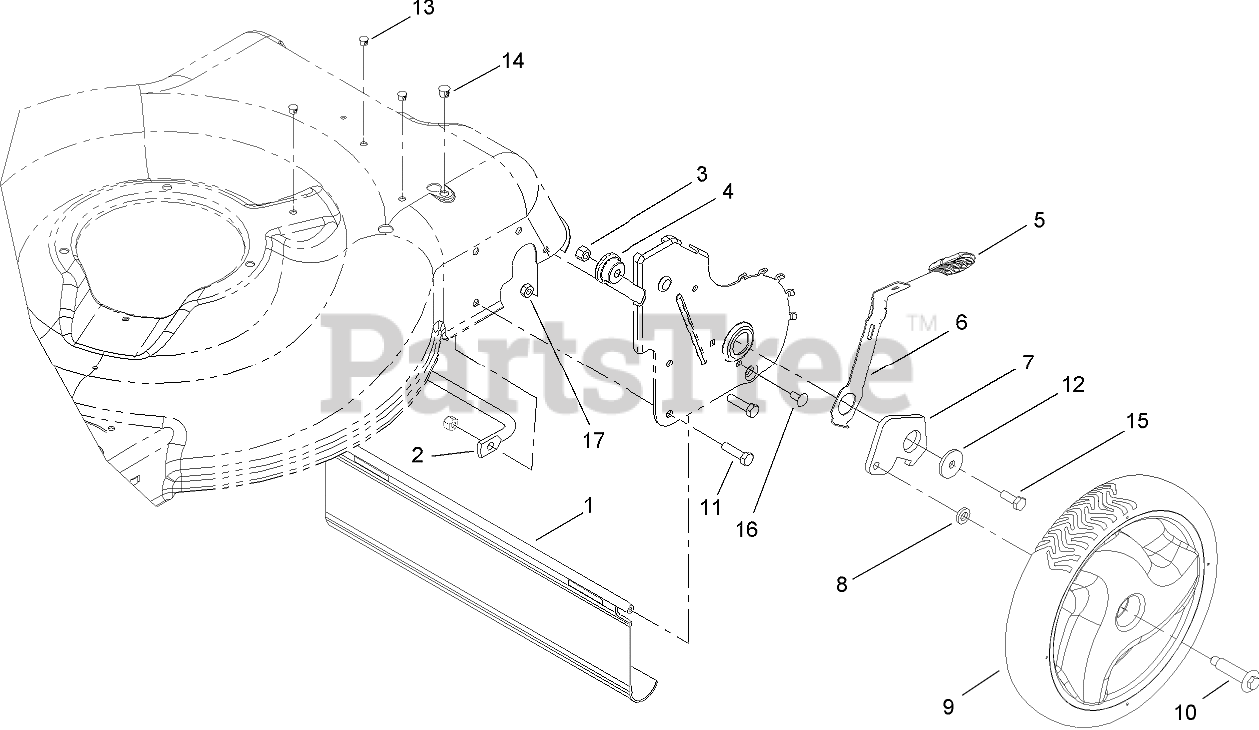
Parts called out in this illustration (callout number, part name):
1	SHIELD-TRAILING
2	BRACE-PLATE, HOC
3	NUT-HEX, SIDE DEFORM
4	BUSHING-MOUNT
5	Knob-Lever, HOC
6	ARM-11 INCH SPRING, REAR
7	Arm-Pivot, Rear (LH)
8	WASHER-BOLT, WHEEL
9	11 INCH WHEEL ASM
10	BOLT-SHOULDER
11	SCREW-HH
12	Washer-Flat
13	Plug-Dome
14	Plug-Dome
15	SCREW-HH
16	SCREW-CARR
17	NUT-LOCK, NI
